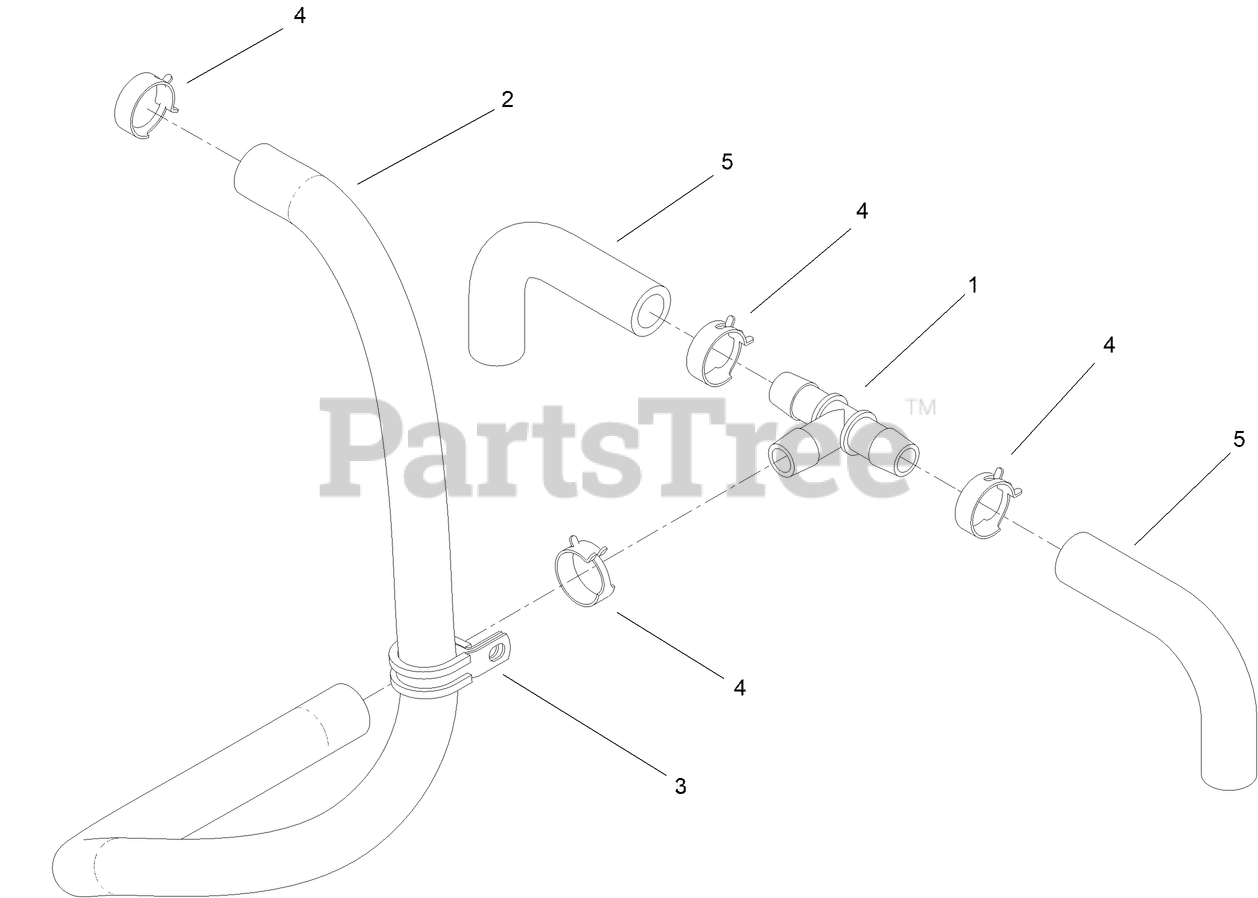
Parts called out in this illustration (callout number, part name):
1	FITTING TEE
2	HYDRAULIC HOSE
3	R-CLAMP
4	HOSE CLAMP
5	HOSE-HYDRAULIC
